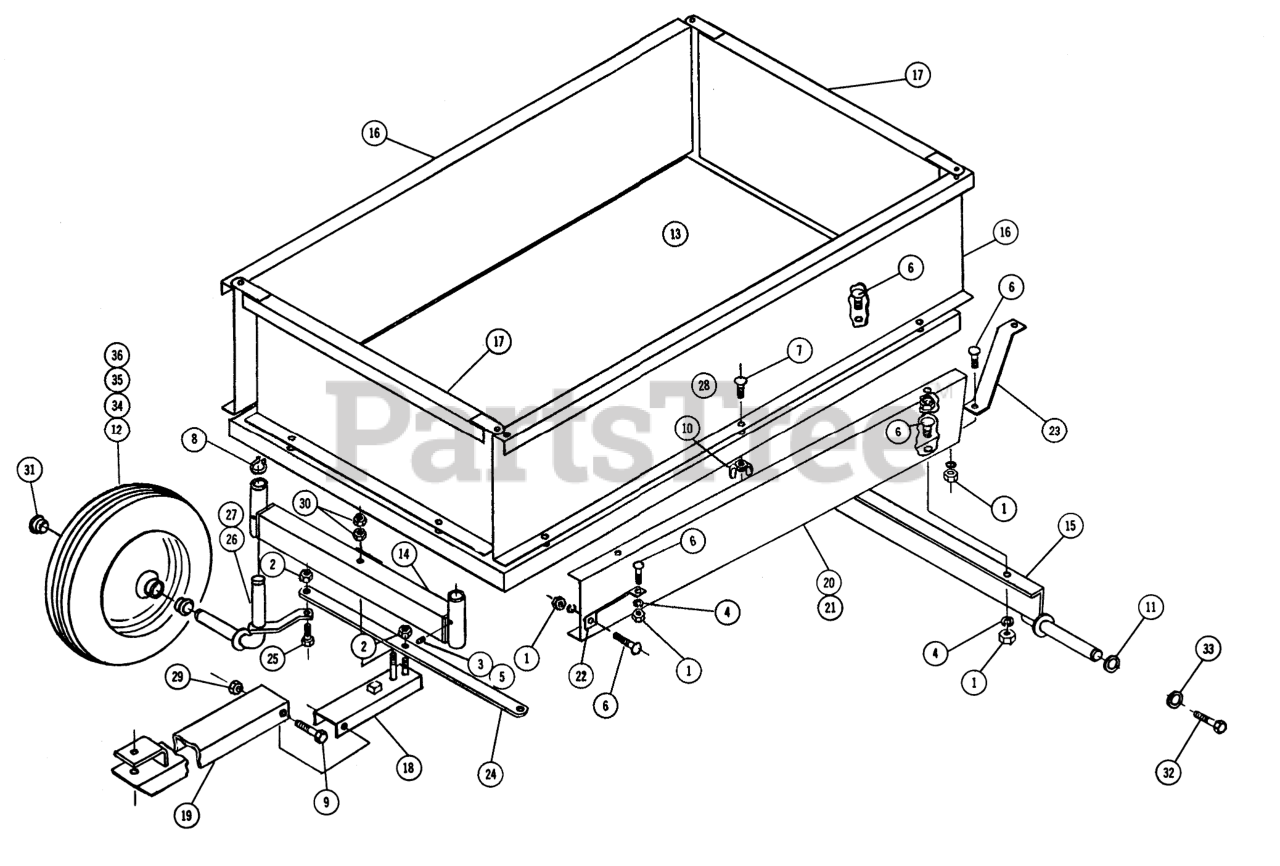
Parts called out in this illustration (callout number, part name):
2	Nut-1/2-13
3	Zerk
4	Lockwasher
5	Washer
6	Bolt-3/8-16 x 3/4
7	Bolt-Carriage
8	E-RING
9	Bolt-Hex 1/2-13 x 3
10	3/8 NC Wing Nut
11	WASHER
12	Tire & Wheel
13	Bed
14	Front Axle Assembly
15	Rear Axle Assembly
16	Side Panel
17	End Panel
18	Swivel Hitch Assembly
19	Draw Bar Assembly
20	Clip
21	Bed Support L.H.
22	Front Brace
23	Rear Brace
24	Tie Rod
25	Clevis Pin
26	Spindle Assembly R.H.
27	Spindle Assembly L.H.
28	Decal
29	Locknut-1/2-13
30	Hex Jam Nut 5/8-11
31	BEARING
32	Bolt 3/8-16 x 7/8
33	WASHER
34	Tire
35	Tube
36	Wheel
